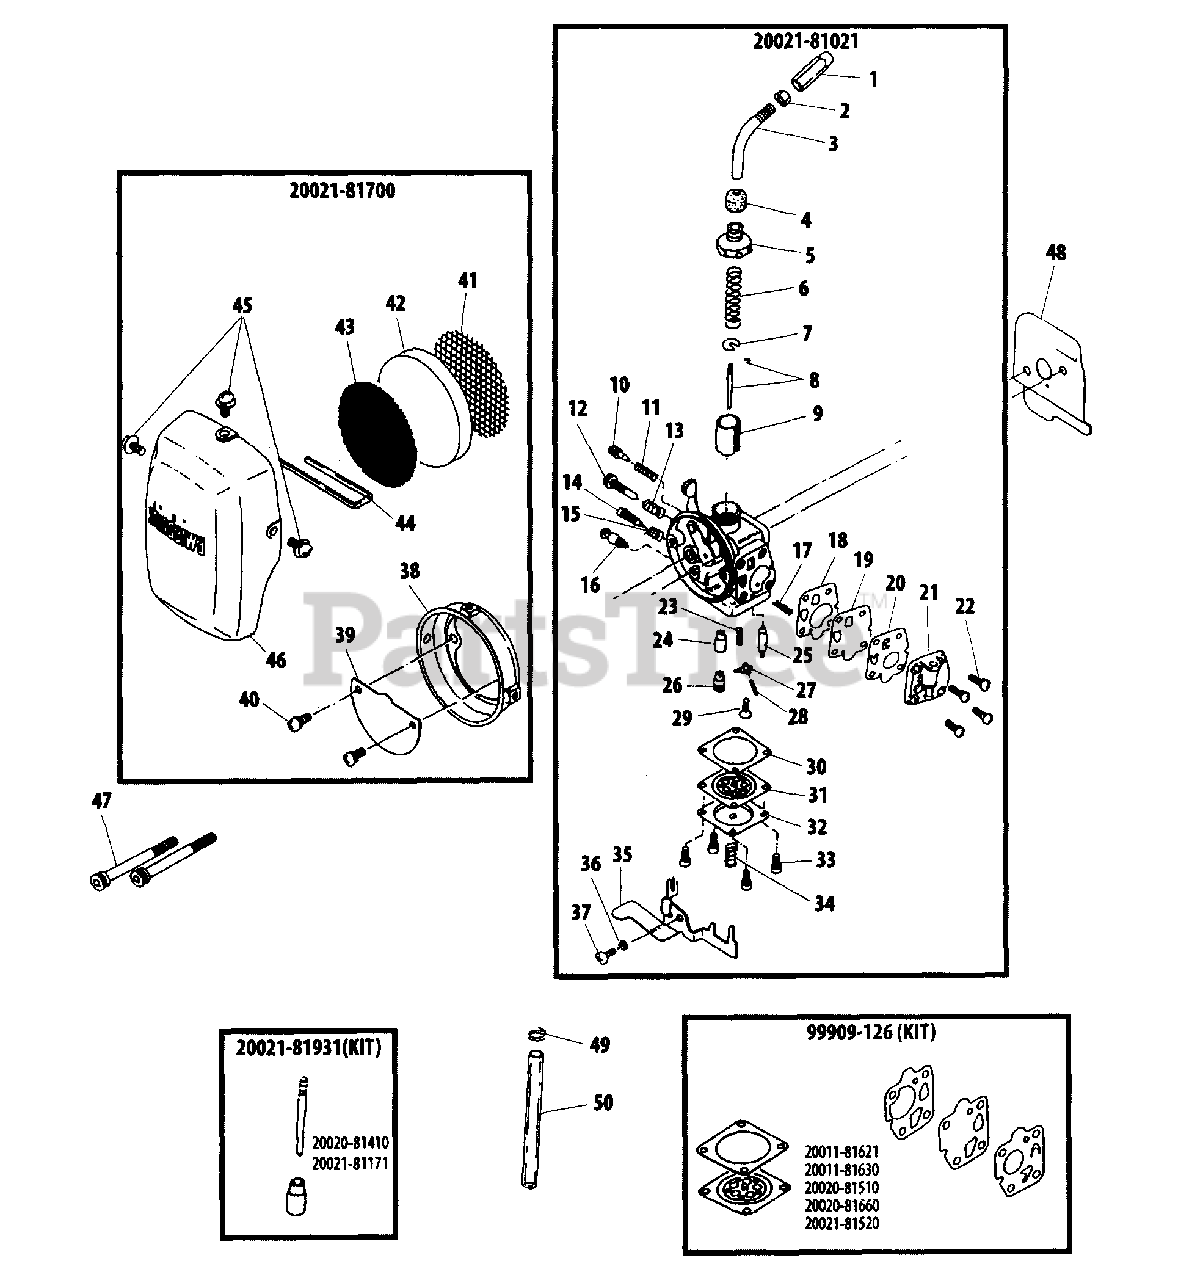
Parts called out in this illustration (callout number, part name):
1	NUT, CABLE ADJUST
2	LOCKNUT
3	GUIDE, CABLE
4	GROMMET
5	CAP, CARBURETOR
6	SPRING
7	SPRING RECIEVE
8	NEEDLE
9	VALVE, THROTTLE
10	SCREW, SLOW AIR
11	SPRING
12	SCREW, IDLE ADJUST
13	SPRING
14	SCREW, ADJUST
15	SCREW, IDLE ADJUST
16	VALVE, OVERFLOW
17	SPRING
18	GASKET, METERING
19	DIAPHRAGM, METERING
20	VALVE, PUMP
21	COVER, PUMP
22	SCREW
23	SPRING
24	JET
25	VALVE, INLET NEEDLE
26	HOLDER, JET
27	LEVER, METERING
28	PIN, METERING LEVER
29	SCREW, METERING LEVER PIN
30	GASKET
31	DIAPHRAGM, METERING
32	COVER, METERING
33	SCREW
34	SPRING
35	LEVER, TICKLER
36	COLLAR
37	SCREW
38	CASE, AIR FILTER
39	PLATE
40	SCREW
41	SCREEN - INNER
42	FILTER, AIR - FOAM
43	SCREEN - OUTER
44	CLIP
45	SCREW
46	COVER, AIR FILTER
47	SCREW - 5X48
48	SHIELD, INTAKE
49	RING, RETAINING - 6
50	PIPE
20021-81021	CARBURETOR
20021-81700	AIR FILTER ASSY
20021-81931	NEEDLE/JET KIT
99909-126	DIAPHRAGM/GASKET KIT
